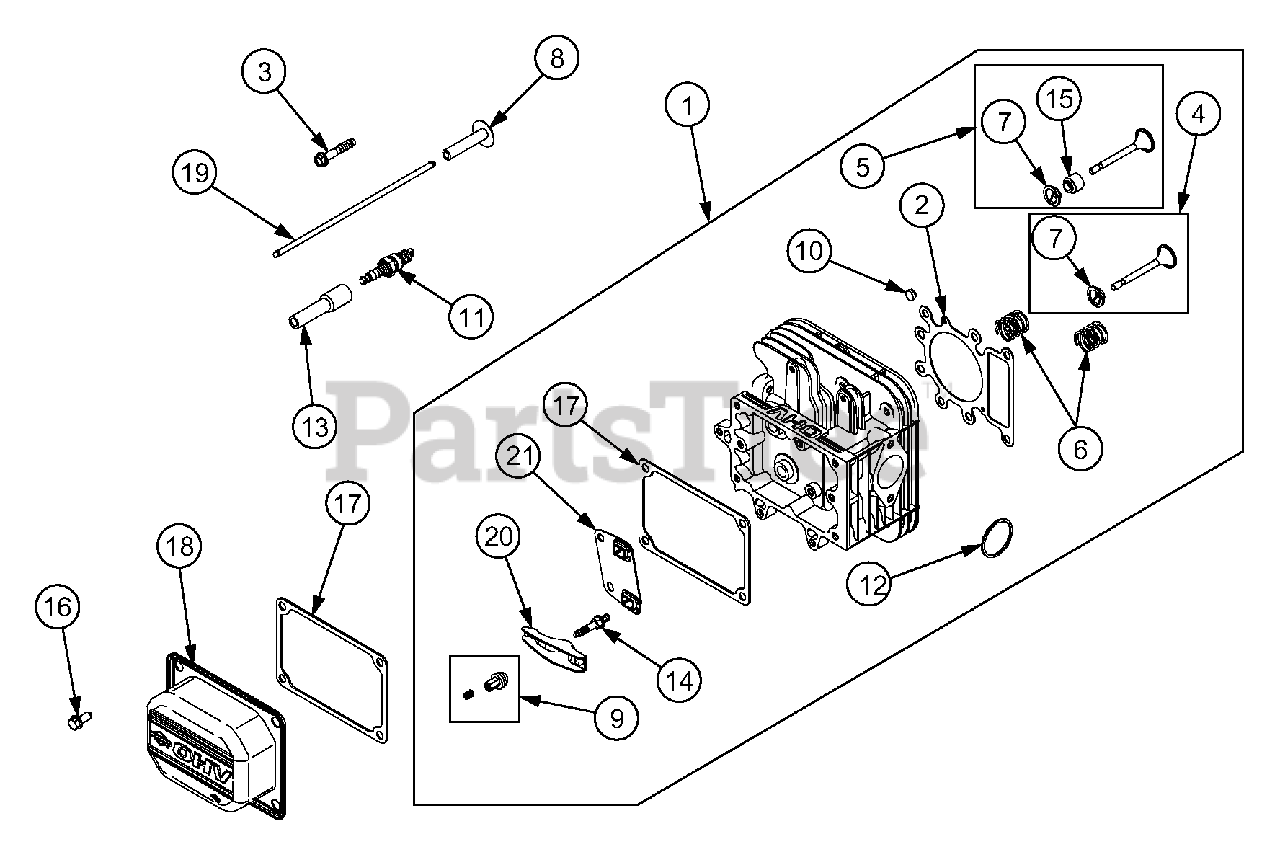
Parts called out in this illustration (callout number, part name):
1	Head, Cylinder
2	Gasket, Cylinder Head
3	Screw, Cylinder Head
4	Valve, Exhaust
5	Valve, Intake
6	Spring, Valve
7	Retainer, Valve
8	Tappet, Valve
9	Adjuster, Rocker Arm
10	Cap, Valve
11	Spark Plug (RC12YC)
12	O-Ring Seal (Intake Manifold)
13	Boot, Spark Plug
14	Stud, Rocker Arm
15	Seal, Valve
16	Screw (Rocker Cover)
17	Gasket, Rocker Cover
18	Cover, Rocker
19	Rod, Push (Intake)
20	Arm, Rocker
21	Guide, Push Rod
